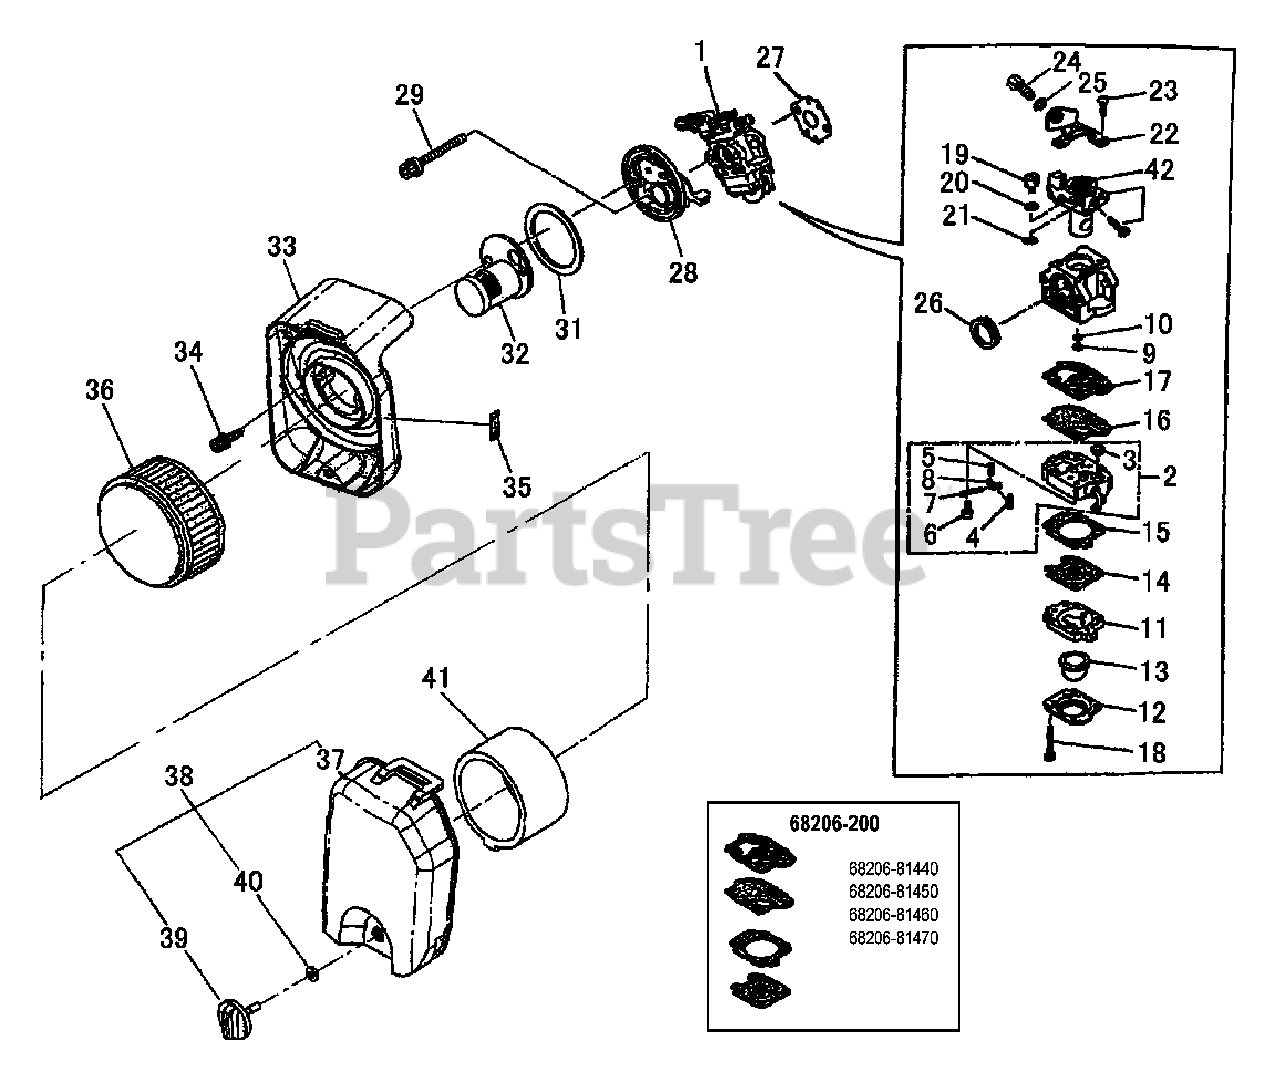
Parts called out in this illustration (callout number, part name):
1	CARBURETOR
2	BODY ASSY, PUMP
3	SCREEN, FUEL INLET
4	VALVE, INLET NEEDLE
5	SPRING, METERING LEVER
6	SCREW, METERING LEVER PIN
7	PIN, METERING LEVER
8	LEVER, METERING
9	JET, MAIN
11	BODY ASSY, PURGE
12	RETAINER, PURGE BULB
13	BULB, PURGE
14	DIAPHRAGM, METERING
15	GASKET, METERING DIAPHRAGM
16	DIAPHRAGM, PUMP
17	GASKET, PUMP
21	RING, SNAP
22	BRACKET, THROTTLE CABLE
23	SCREW, THROTTLE COLLAR
24	ADJUSTER, THROTTLE CABLE
26	RING, PACKING
27	GASKET, INTAKE
28	CHOKE ASSY
29	BOLT M5×50
31	GASKET, INTAKE
32	PIPE, INTAKE
33	CASE, AIR FILTER
34	BOLT M4×14
35	LABEL, CHOKE
36	FILTER, AIR
37	COVER, AIR FILTER
38	COVER ASSY, AIR FILTER
39	THUMBSCREW
40	WASHER 5
41	PRE-FILTER, FOAM
42	VALVE ASSY, THROTTLE
68206-200	GASKET/DIAPHRAGM KIT
68206-81440	DIAPHRAGM
68206-81460	DIAPHRAGM
68206-81470	GASKET, PUMP
